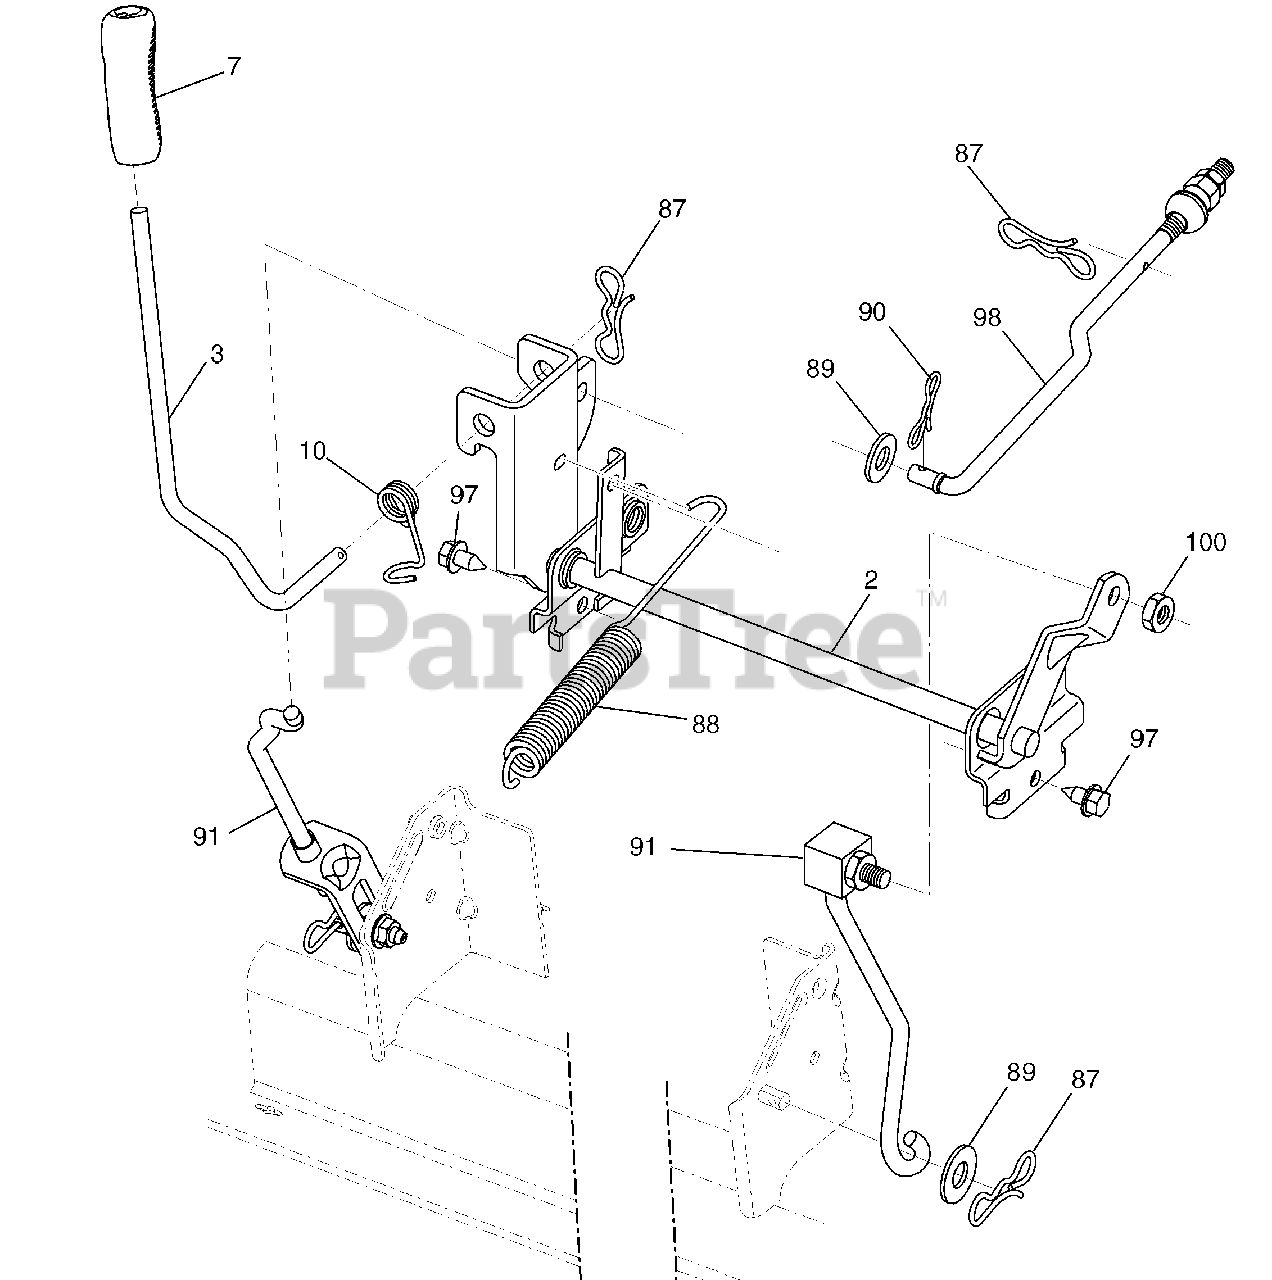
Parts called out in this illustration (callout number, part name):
2	Shaft Asm., Lift
3	Lever Asm., Lift Rh
7	Grip, Lever
10	Spring Torsion
87	Pin Cotter 7/16 Bow Tie Lock
88	Spring Lift Assist
89	Washer Clear Zinc
90	Pin Cotter 5/16 Bow Tie Lock
91	Link Lift Susp Mower Rear
97	Screw 3/8-16 x 3/4
98	Link Lift Susp. Front Mower
100	Nut Center Lock 3/8-16 UNC
